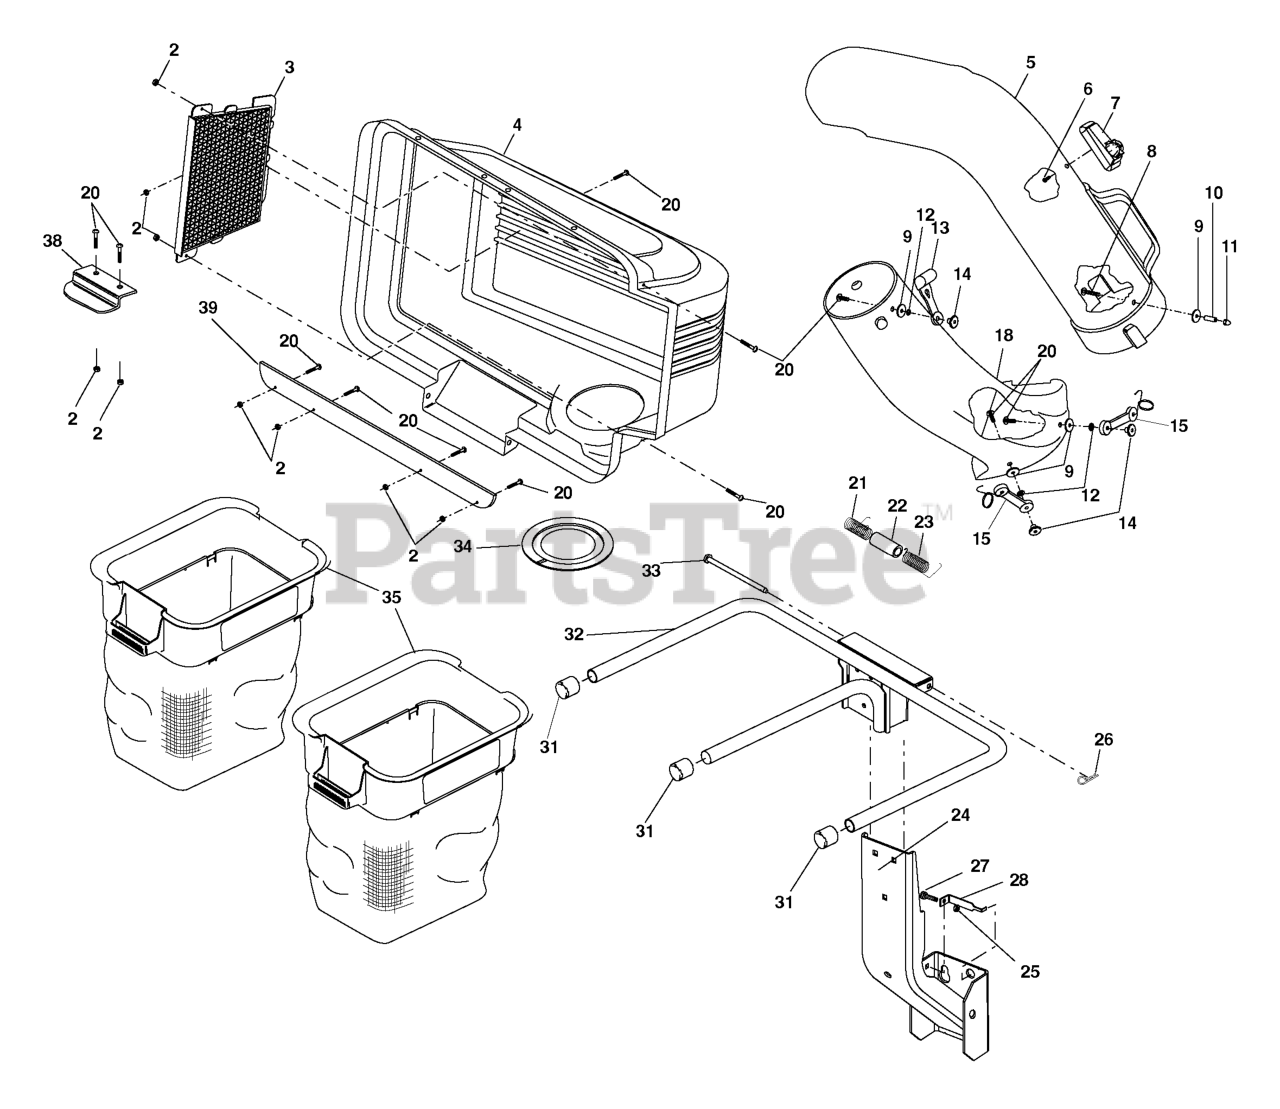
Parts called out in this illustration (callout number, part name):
3	COVER SCREEN
4	COVER.ASM.BAG.W/STRIP
5	CHUTE.UPPER.42"
7	INDICATOR ASM BAG
8	SCREW
11	NUT
12	LOCKWASHER #10
13	LATCH.HOOD.
14	WELDNUT
15	LATCH ASSY
18	LOWER CHUTE FOR 42" BAGGER
20	SCREW
21	SPRING COVER LH
22	SPACER.COVER.BAGGER
23	SPRING COVER RH
24	POST.SUPPORT.BAGGER.BLACK
25	LOCKNUT.NYLOC.1/4-20
26	RETAINER-SPRNG RB
28	STOP BRACKET, BAGGER 2 BIN
31	PLUG, TUBING END
32	FRAME.ASM.BAGGER.2BIN.QC42B
33	BAGGER.HINGE.PIN
34	GASKET.COVER.BAGGER
35	CONTAINER BAG, SOFT
38	LATCH CER38
39	STRIP.REINFORCE.BAGGER.2BIN.BL
